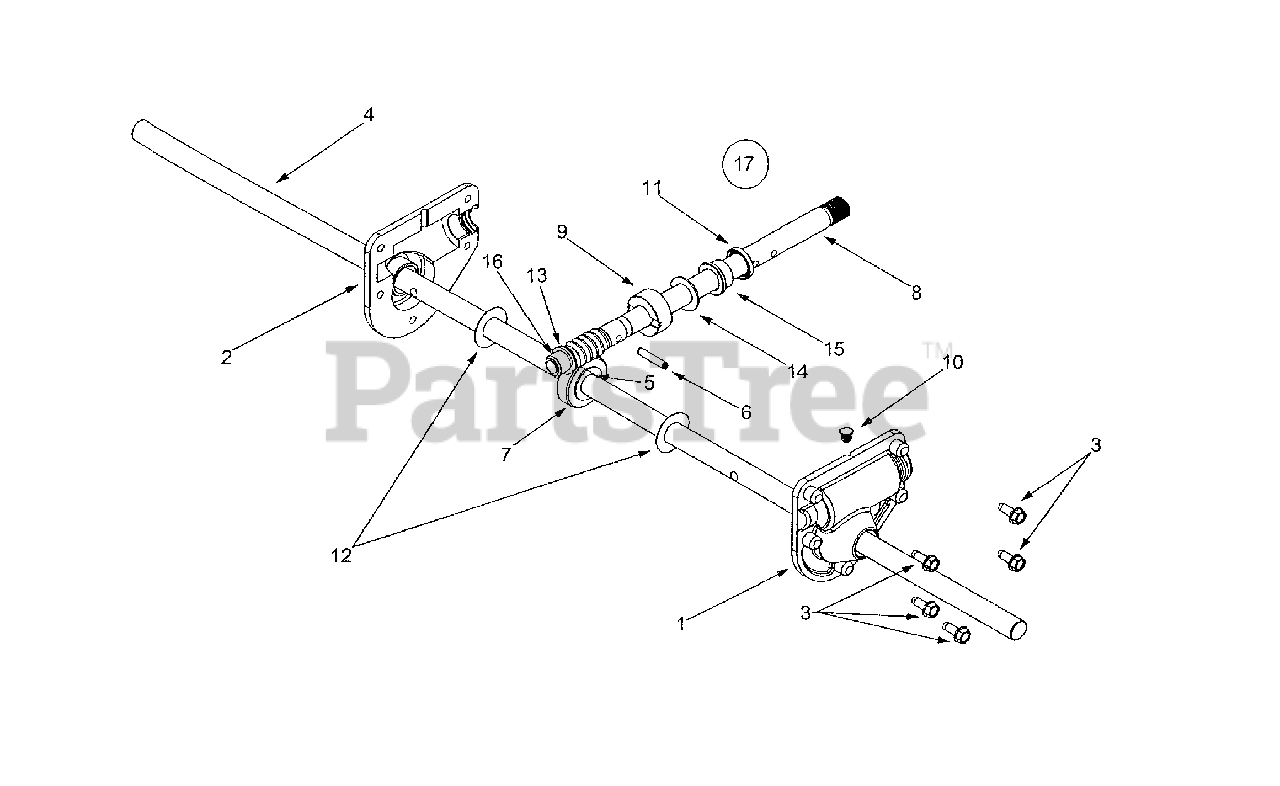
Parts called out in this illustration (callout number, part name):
1	RH Reducer Housing
2	LH Reducer Housing
3	Hex Screw 1/4-20 x .75
4	Spiral Axle 24"
5	Key
6	Pin-Spiral
7	Worm Gear, 20T
8	Worm Shaft
9	Thrust Collar
10	Grease Plug
11	Grease Seal
12	Flat Washer .76 x 1.5 x .030
13	Flat Washer .508 x 1.0 x .020
14	Flat Washer.76 x 1.5 x .060
15	Flange Bearing .75 x 1.0 x .59
16	Flange Bearing .75 x 1.0 x .925
17	Ass'y. Complete 24"
